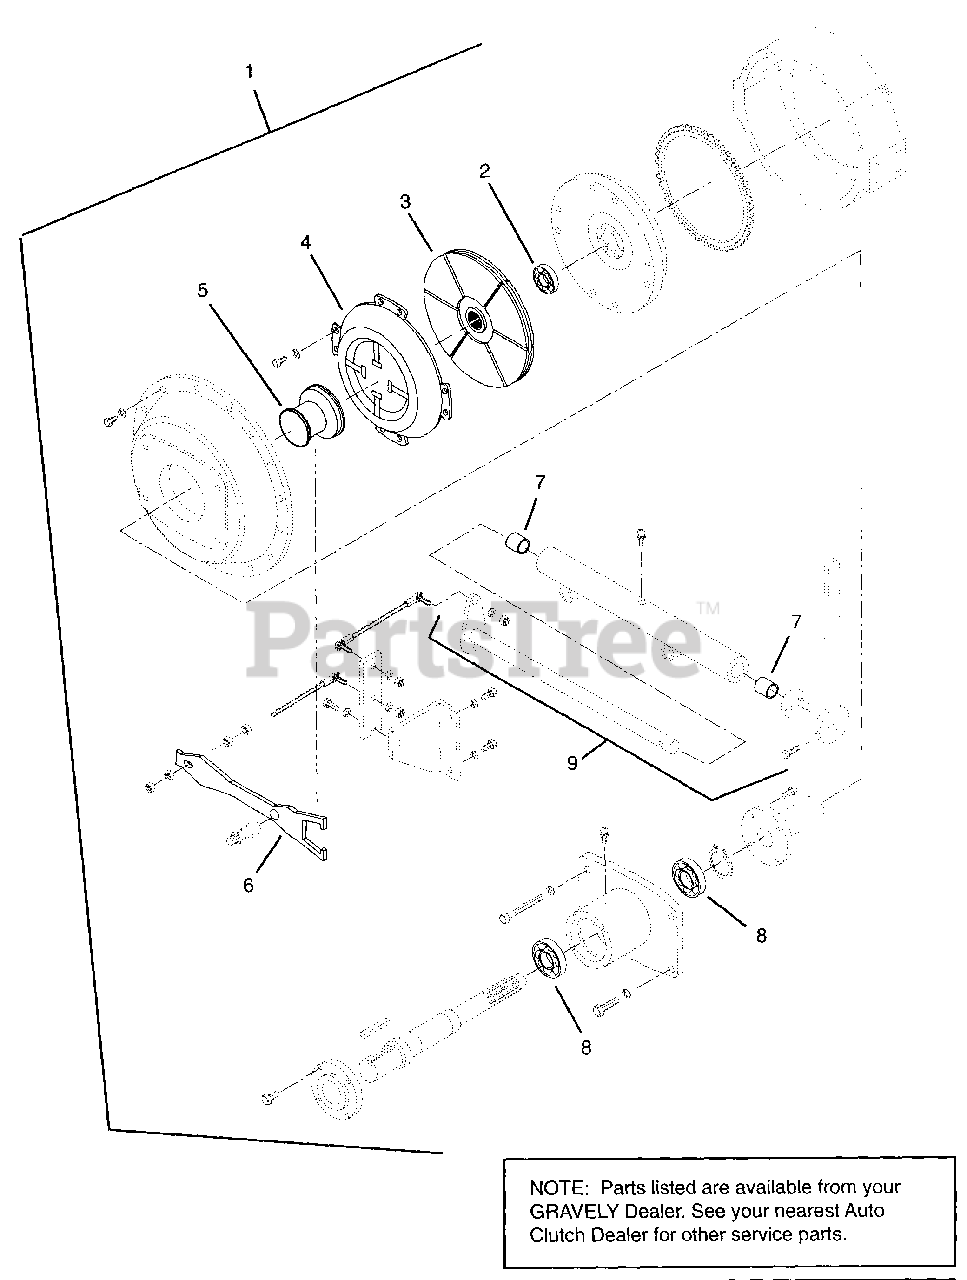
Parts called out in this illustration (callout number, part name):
1	Clutch Assembly
2	Pilot Bearing
3	Disk, Clutch
4	Plate, Pressure Clutch
5	Bearing, Throw-Out
7	Bushing, Shaft
8	Bearing, PTO
9	Shaft - Clutch Release Assembly
